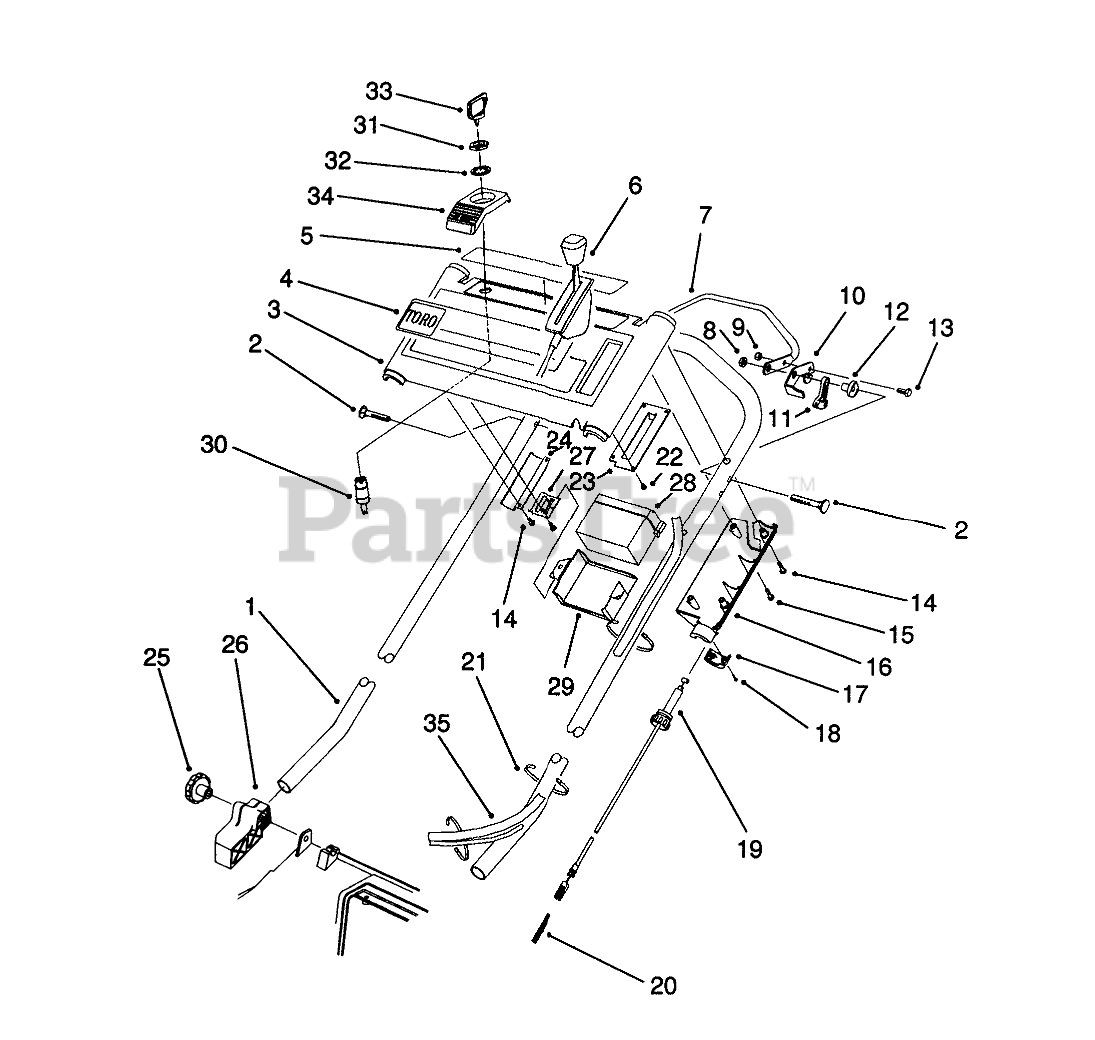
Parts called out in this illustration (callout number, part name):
1	Handle
2	SCREW-HANDLE
3	Panel-Control (Inch Ref. #4, & 5)
4	DECAL - TORO
5	DECAL - DANGER PANEL
6	Control-Throttle Bend Type #1 Sheath Lg. 42.50 Wire Lg. 2 1/2
7	CONTROL BAR
8	NUT-LOCK, NI
9	NUT-LOCK, NI
10	CONTROL LEVER
11	LEVER-TRACTION
12	SPACER-SUPPORT
13	SCREW-HH
14	SCREW-PPH, PLASTITE
15	Screw
16	Cover-Throttle Lower
17	LOWER THROTTLE CAP
18	#4-14X.62 PLASTITE SCW
19	TRACTION CABLE
20	SPRING-COMPRESSION
21	TIE-CABLE
22	#6-19X.25 PLASK FORM SC
23	THROTTLE PLATE
24	Bracket-Panel
26	MOUNT-HANDLE, RH
27	BATTERY BRACKET
28	Battery
29	BATTERY RETAINER
30	Switch-Starter (Incl . Ref . #31, & 32)
31	NUT-HH
32	WASHER-TOOTH, INTERNAL
33	KEY-IGNITION
34	IGNITION SWITCH BRACKET
35	WIRE HARNESS
